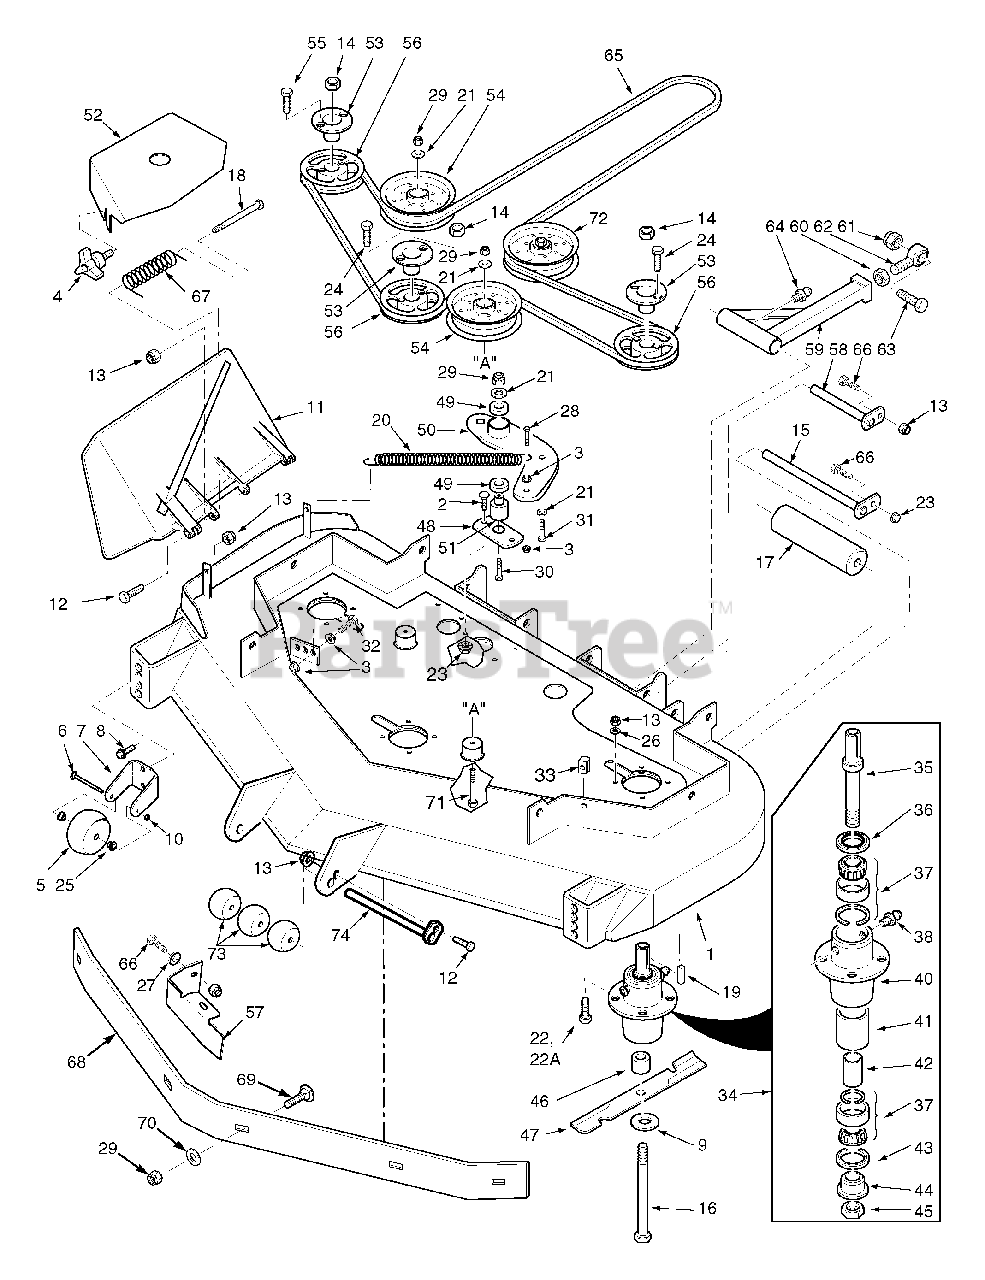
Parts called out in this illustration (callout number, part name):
1	Cutter Deck Advantage
2	Bolt, Carr. 5/16-18 x 1"
3	Nut, 3/8-16 Serrated Flange
4	Wing Nut, 3/8-16
5	Anti-Scalp Wheel
6	Bolt, Carriage 3/8-16 x 4"
7	Bracket, Anti-Scalp Wheel
8	Bolt, Serrated Flange 3/8-16 x 1"
9	Flatwasher, 5/8" Hardened
10	Locknut, 3/8-16 Center Lock
11	Discharge Chute
12	Bolt, Hex Head 5/16-18 x 1-1/2", Rear
13	Nut, Elastic Stop 5/16-18
14	Nut, 5/8-11 UNC
15	Shaft, Roller
16	Bolt, Hex Head 5/8-11 x 9-1/2"
17	Roller, Rear
18	Bolt, Hex Head 5/16-18 x 4-3/4"
19	Key, 1/4 x 1/4 x 2"
20	Spring, Idler
21	Flatwasher, 3/8" - .938 x .391 x .105
22	Bolt, Hex Head 5/16-18 x 1-3/4" Grade 8
23	Nut, Serrated Flange 5/16-18
24	Bolt, Hex Head 1/4-20 x 1" Grade 8
25	Bushing, .376 ID Oilite
26	Lockwasher 5/16"
27	Flatwasher 5/16"
28	Bolt, 3/8-16 x 1-1/2" Grade 8
29	Nut, Elastic Stop 3/8-16
30	Bolt, Hex Head 3/8-16 x 2-1/2"
31	Bolt, Hex Head 3/8-16 x 3"
32	Bolt, Hex Head 3/8-16 x 1-1/2 Grade 8
33	U-Nut, 3/8-16
34	Spindle Assembly
35	Shaft, Spindle
36	Seal Upper
37	Bearing Assembly
38	Grease Fitting
39	Valve, Grease Relief
40	Housing, Spindle
41	Spacer, Outside
42	Spacer, Inside
43	Seal, Lower
44	Bushing, Bottom
45	Nut, Special 1-1/16 - 18
46	Spacer, Spindle
47	Cutter Blade 21"
48	Pivot, Idler Base
49	Bearing
50	Idler Arm Assy.
51	Idler Pivot, Short
52	Belt Cover (61A)
53	Hub, Tapered 1-1/8" Bore
54	Pulley, Idler 5.0"
55	Bolt, Hex Head 1/4-20 x 1"
56	Pulley, 5.95 Dia. Tapered Bore
57	Turbo Baffle, Bolt On
58	Push Arm Shaft
59	Push Arm
60	Nut, 5/8-18 UNF
61	Nut, Elastic Stop 5/8-11
62	Rod End, 5/8 Male RH Thread
63	Bolt, Hex Head 5/8-11 x 4-1/2"
64	Grease Fitting, 90 Degree
65	Belt, Cutter Deck Drive (61A)
66	Bolt, Hex Head 5/16-18 x 1"
67	Spring, Discharge Chute
68	Baffle Weldment, 61A
69	Bolt, Carriage 3/8-16 x 1"
70	Flatwasher, 3/8-.391 x .938 x .105
71	Bolt, Hex Head 3/8-16 x 3-3/4"
72	Pulley, Idler 5.0" OD
73	Wheel, Anti Scalp
74	Roller Shaft
